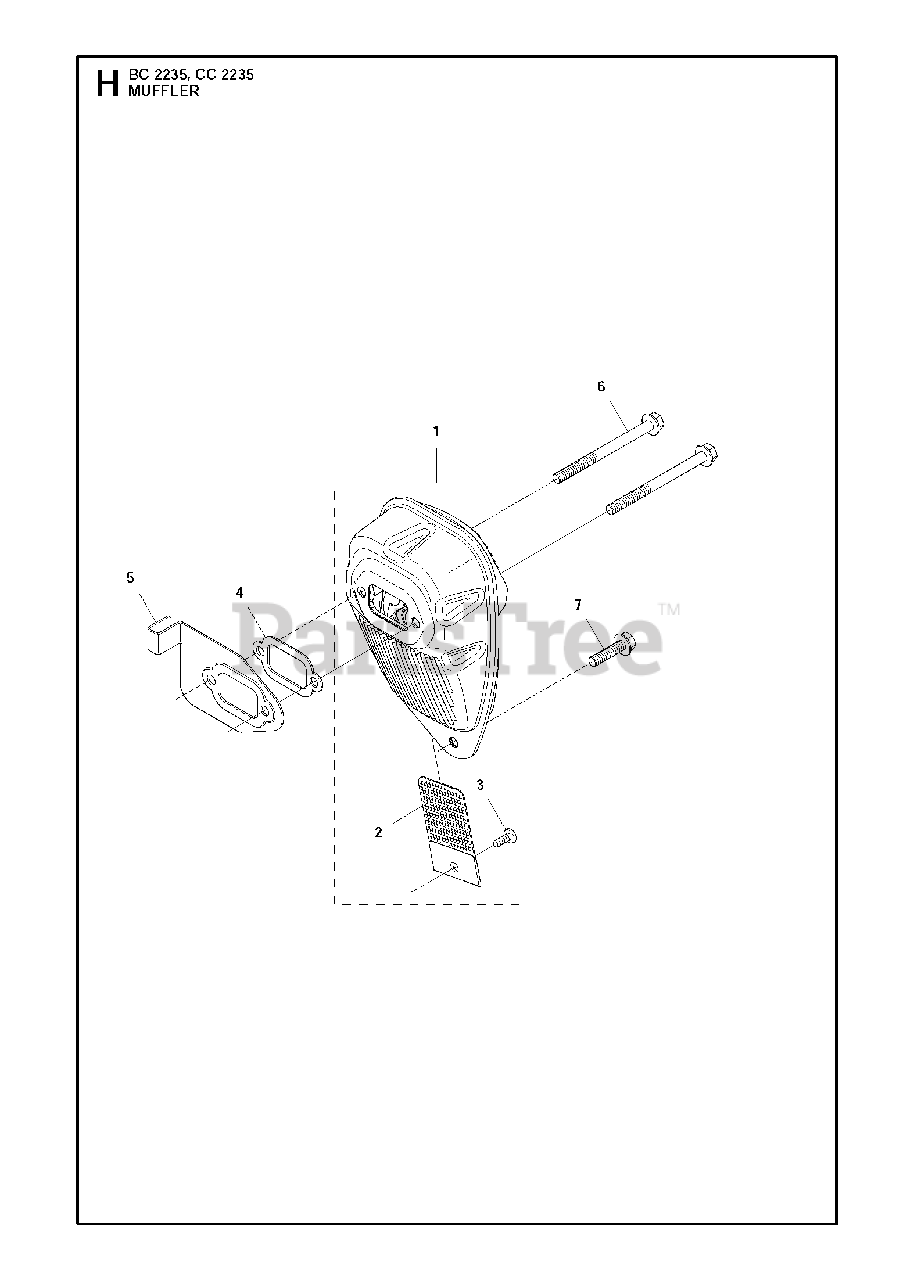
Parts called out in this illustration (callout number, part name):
1	MUFFLER
2	SPARK ARRESTER
3	SCREW
4	GASKET MUFFLER
